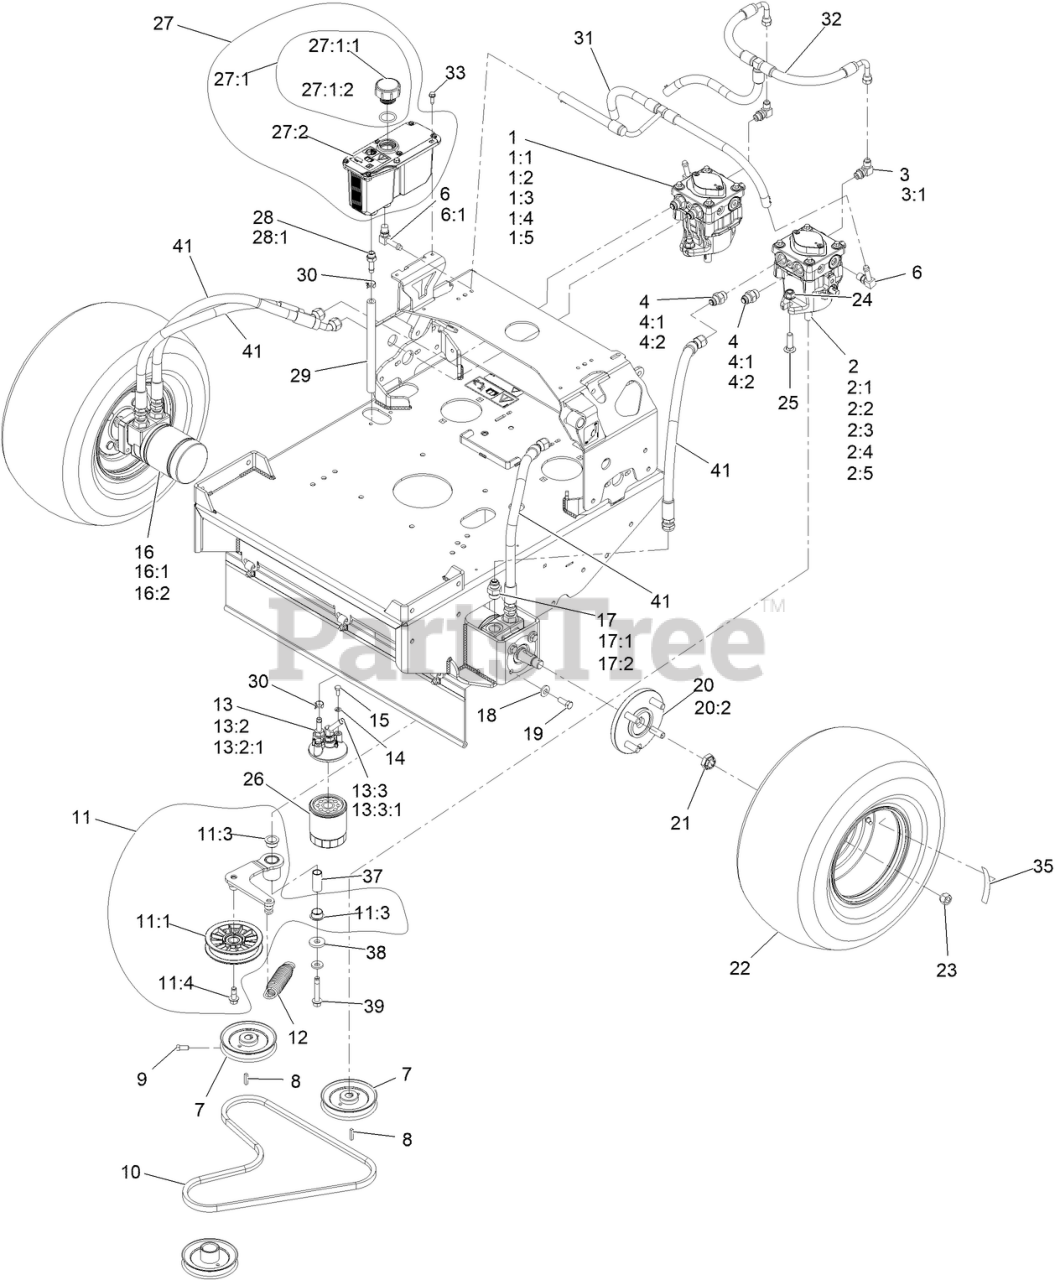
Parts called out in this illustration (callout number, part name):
1	PUMP-HYD PE RH TTH
1:1	INPUT SHAFT KIT
1:2	BEARING-THRUST
1:3	CYLINDER BLOCK KIT
1:4	SEAL OVERHAUL KIT
1:5	KIT, 10CC/12CC PUMP KIT
2	PUMP-HYD PE LH TTH
2:1	INPUT SHAFT KIT
2:2	BEARING-THRUST
2:3	CYLINDER BLOCK KIT
2:4	SEAL OVERHAUL KIT
2:5	KIT, 10CC/12CC PUMP KIT
3	FITTING-ELBOW, 90 DEG
3:1	O-RING
4	FITTING-STRAIGHT
6	FITTING-ELBOW, 90
6:1	O-RING
7	SHEAVE ASM
9	SCREW-SET, SQH
10	BELT
11	ASM, PUMP IDLER
11:1	PULLEY-IDLER, FLAT
11:3	BUSHING-FLANGE
11:4	SCREW-HFH
12	SPRING-EXTENSION
13	ASM, FILTER HEAD
13:2	ADAPTER-STRAIGHT
13:2:1	O-RING
13:3	FITTING-BARBED, 45 DEG
13:3:1	O-RING
14	WASHER-LOCK
15	SCREW-HH
16	HYD MOTOR ASM
16:1	SEAL KIT
16:2	BEARING AND SEAL KIT
17	FITTING-STRAIGHT
17:1	O-RING
18	WASHER-BELLEVILLE
19	SCREW-HH
20	WHEEL HUB ASM
20:2	STUD-WHEEL
21	NUT-LOCK
22	ASM, DRIVE TIRE
23	NUT-LUG
24	NUT-HF, NI
25	BOLT-CARR
26	FILTER-25 MICRON, BI-DIRECTIONAL
27:1	RESERVOIR-HYD
27:1:1	Cap-Reservoir, HYD
27:2	DECAL-WARNING
28	ADAPTER-STRAIGHT
28:1	O-RING
29	HOSE-CHARGE
30	CLAMP-HOSE
31	HOSE, CASE
32	HOSE, CHARGE
33	SCREW-HWH, THREAD ROLL
35	DECAL-TORQUE WHEEL LUG-HU
37	PIVOT, IDLER
39	SCREW-HHF
41	HOSE,HYDRAULIC W/COVER
